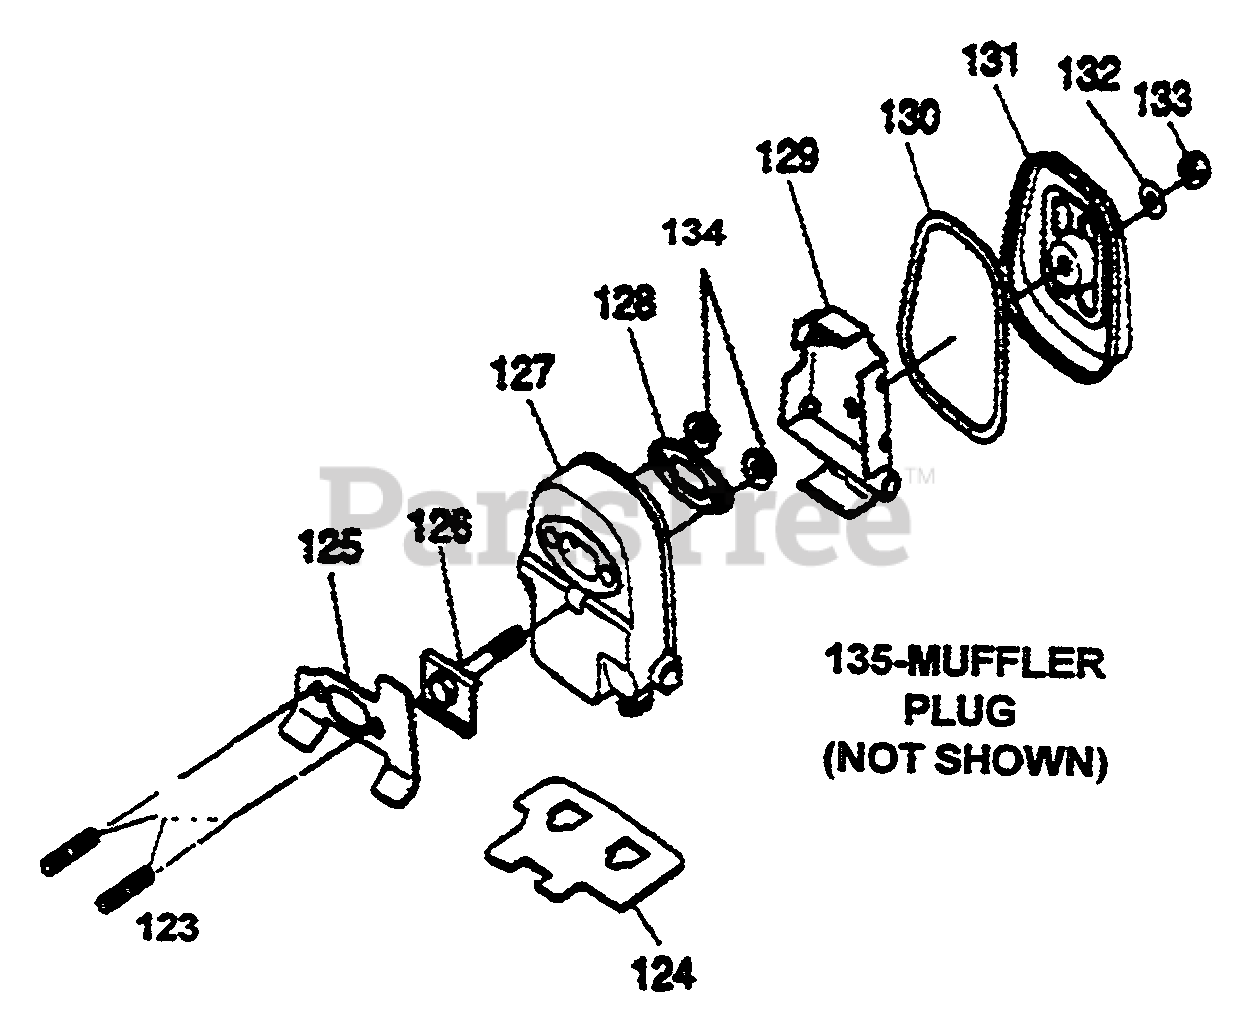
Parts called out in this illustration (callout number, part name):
125	GASKET MUFFLER
126	BOLT, FLANGE
127	BODY, MUFFLER
130	GASKET MUFFLER SEAL
131	LID, MUFFLER
132	WASHER,SEAL
